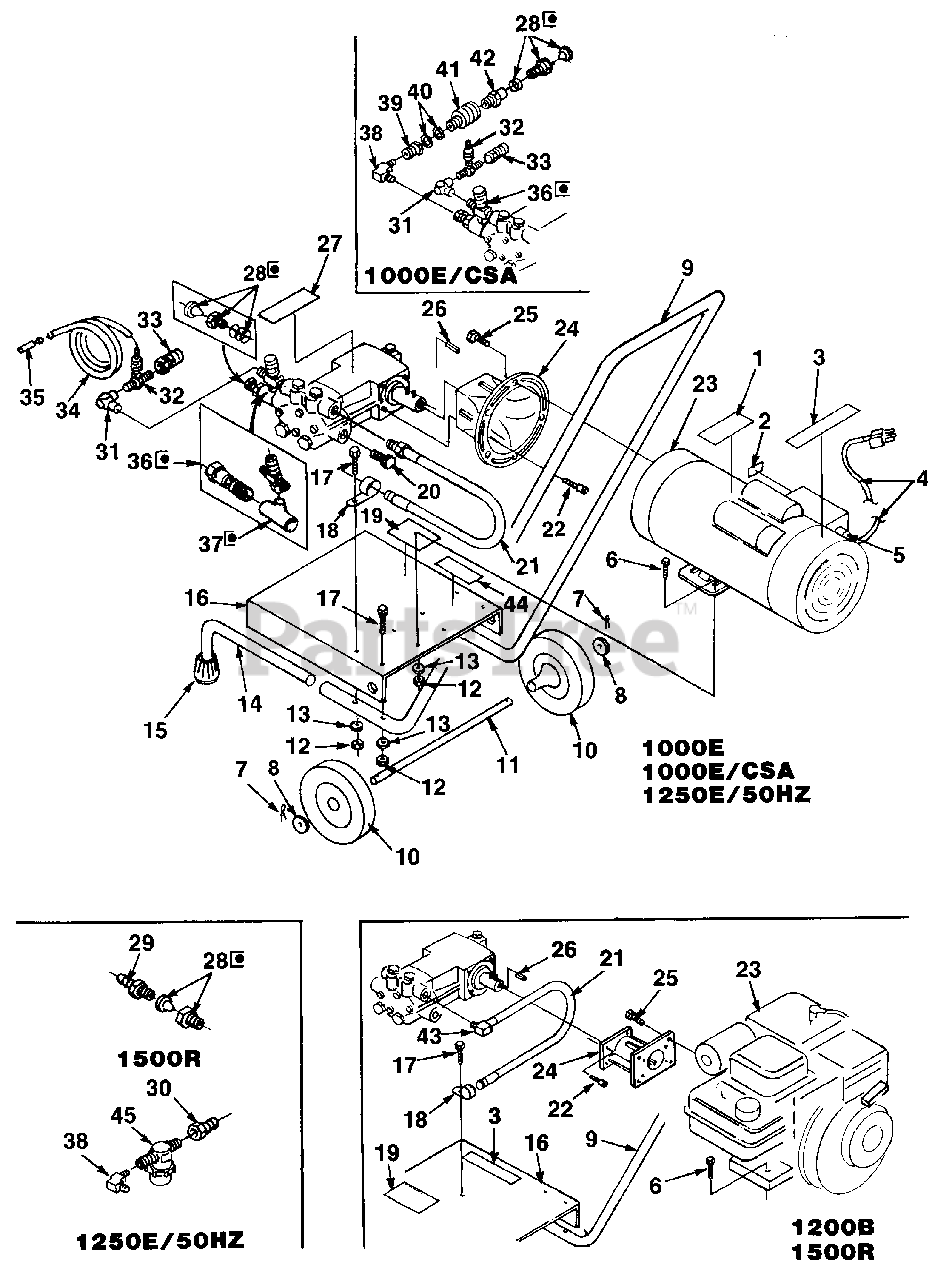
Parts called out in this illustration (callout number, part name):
1	USE A01372A
2	Not used on this product
4	ELECT. CORD
6	BOLT- (5/16-18 x 3/4")
7	COTTER PIN (RDP3) TBO
10	WHEEL & TIRE
13	3WASHER(HPW1200B) TBO
15	RUBBER TIP
17	SCREW - Hex Hd. (5/16-18 X 1 3/4")
19	OPER DECAL
20	PLUG1/2(HPW1200B) TBO
21	PULSE HOSE(HPW1000E TBO
27	ELECT. DECAL
28	SPRING & ADAPTOR
33	FEMALE SOCKE TBO
35	STRAINER
38	STREET ELBOW
39	ADAPTER
41	B FLOW PREVENT
42	ADAPTER
44	FLAM. DECAL
